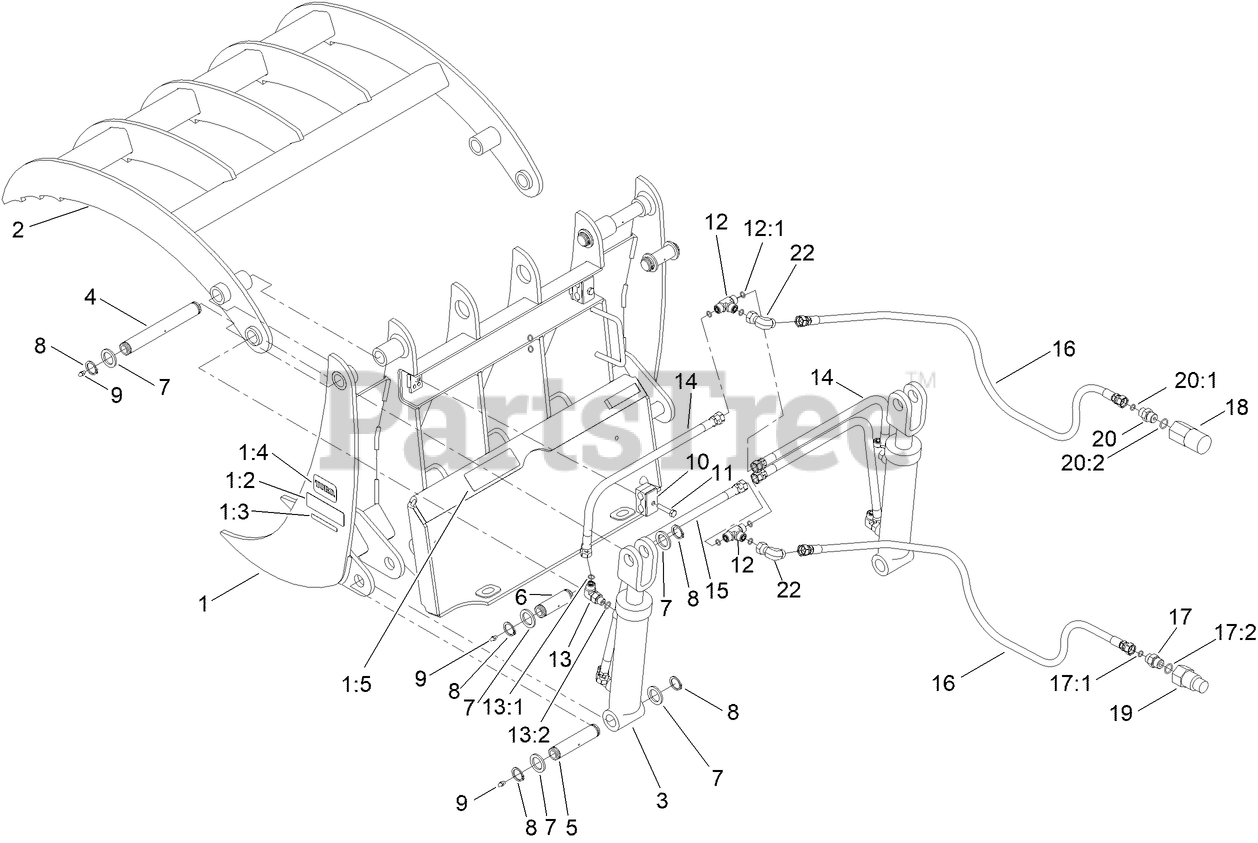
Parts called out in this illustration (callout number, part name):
1	FRAME-GRAPPLE
1:2	DECAL-WARNING
1:3	DECAL-WARNING
1:4	DECAL
1:5	DECAL-CAPACITY
2	JAW-GRAPPLE
3	CYLINDER-HYD
4	PIN-PIVOT
5	PIN-PIVOT
6	PIN-PIVOT
7	SPACER-HARDENED
8	RING-RETAINING
9	FITTING-ZERK
10	CLAMP-HOSE
11	SCREW-HH
12:1	O-RING
13	FITTING-ELBOW, 90 DEG
13:1	O-RING
13:2	O-RING
14	HOSE-HYD
15	HOSE-HYD
16	HOSE-HYD
17	FITTING-STRAIGHT
17:1	O-RING
17:2	O-RING
18	COUPLER-FEMALE
19	COUPLER-MALE
20	FITTING-STR,ORIF
20:1	O-RING
20:2	O-RING
22	FITTING-HYD, 90 DEG
